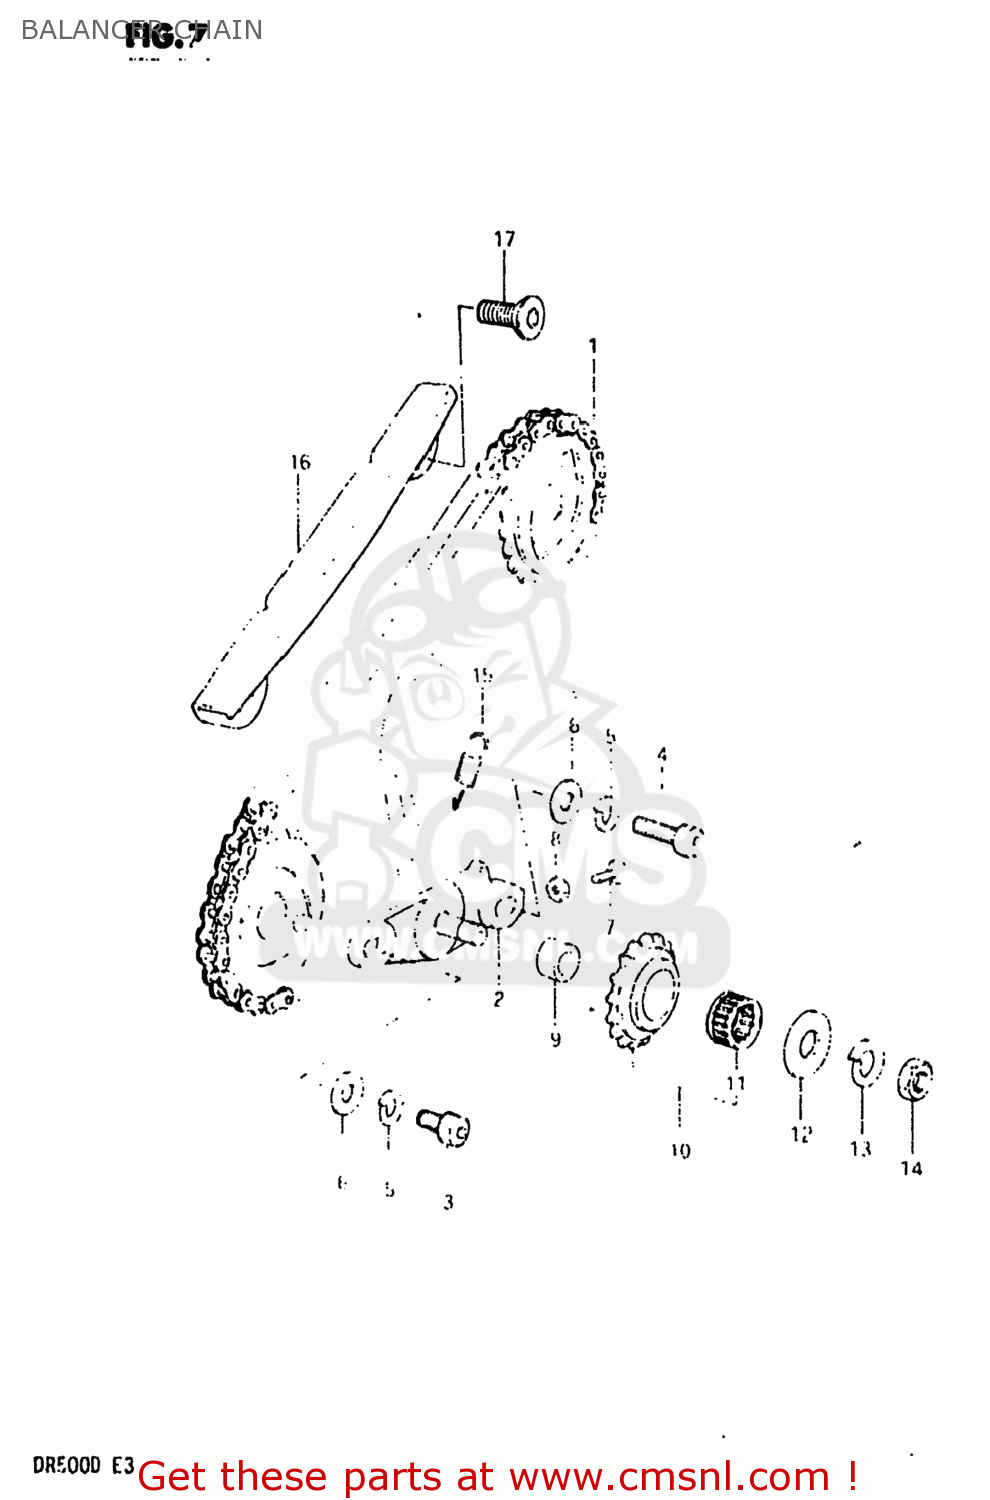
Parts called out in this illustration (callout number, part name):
1	GOVERNOR ASSEMBLY,EXHAUST
2	BRACKET,BALANCER CHAIN TENSIONER
3	BOLT(8X22)
4	BOLT
5	LOCK WASHER
6	WASHER
7	BOLT 5X20
8	NUT
9	SPACER,TENSIONER SPROCKET
10	ROD,EXHAUST VALVE
11	BEARING(17X23X12)
12	WASHER
13	WASHER,LOCK 12
14	NUT
15	SPRING
16	GUIDE,BALANCER CHAIN
17	SCREW
